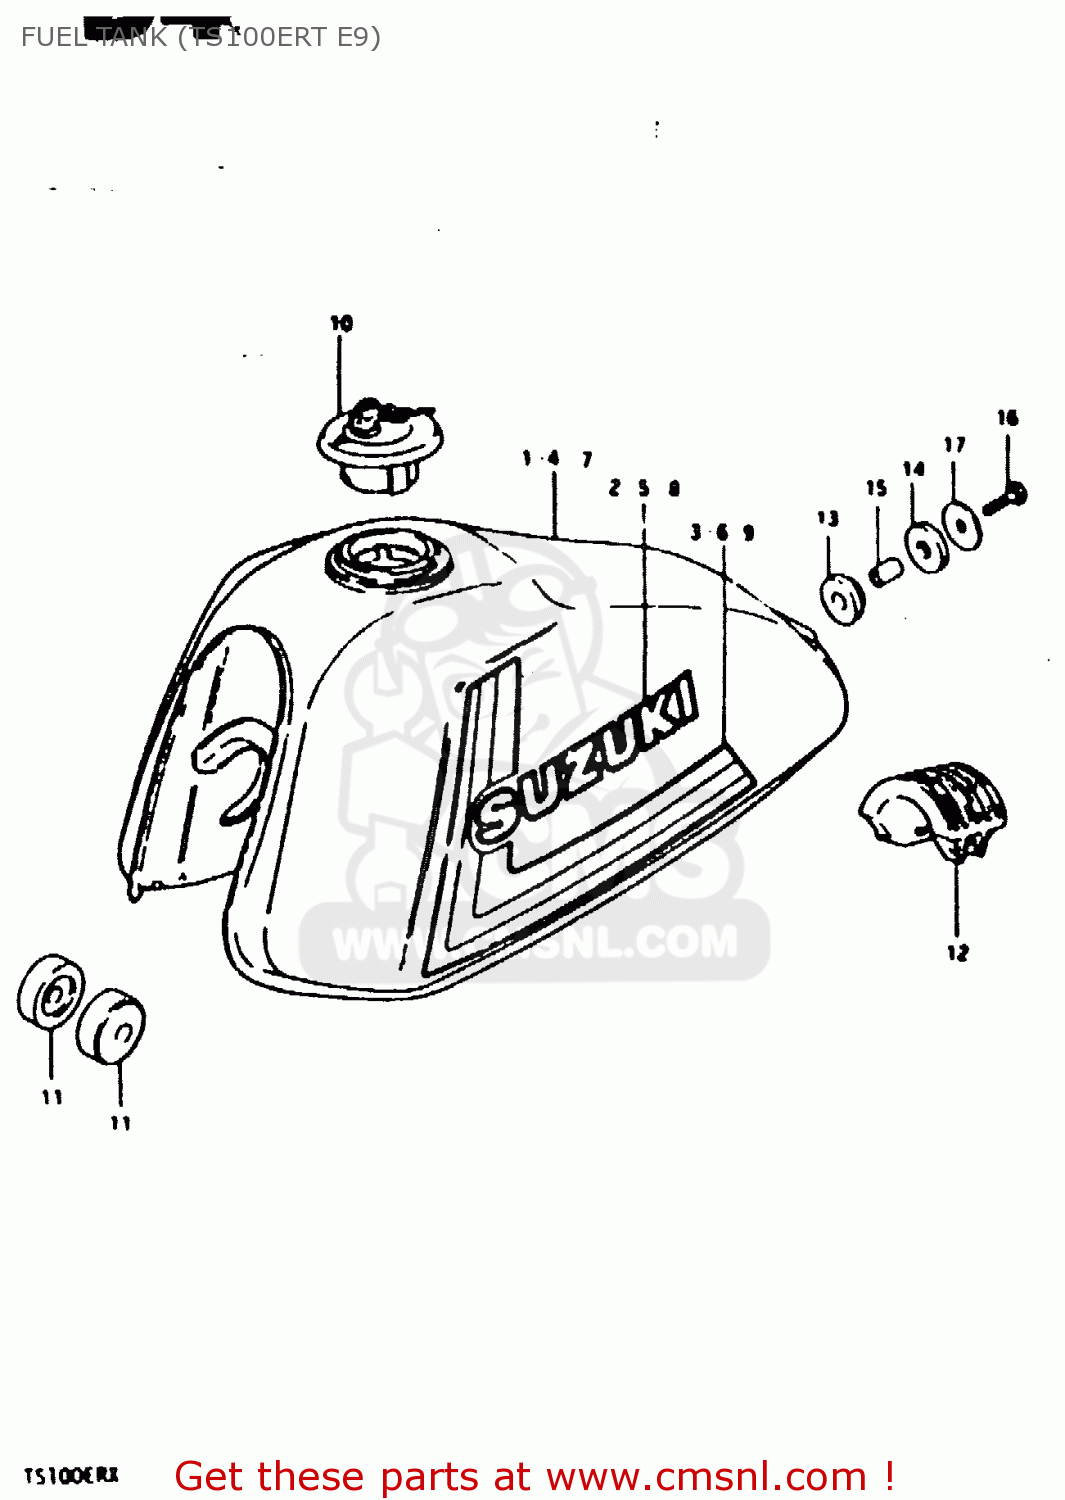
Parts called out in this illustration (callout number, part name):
1	TANK, FUEL (RED)
2	EMBLEM
3	TAPE SET
4	TANK, FUEL (BLUE)
5	EMBLEM
6	TAPE SET
7	TANK, FUEL (WHITE)
8	EMBLEM(BLACK)
9	TAPE SET
10	CAP SET,FUEL TANK
11	CUSHION
12	CUSHION,FUEL TANK
13	CUSHION
14	CUSHION
15	SPACER(8.5X12X19)
16	BOLT (8X30)
17	WASHER (8.5X29X1.6)
